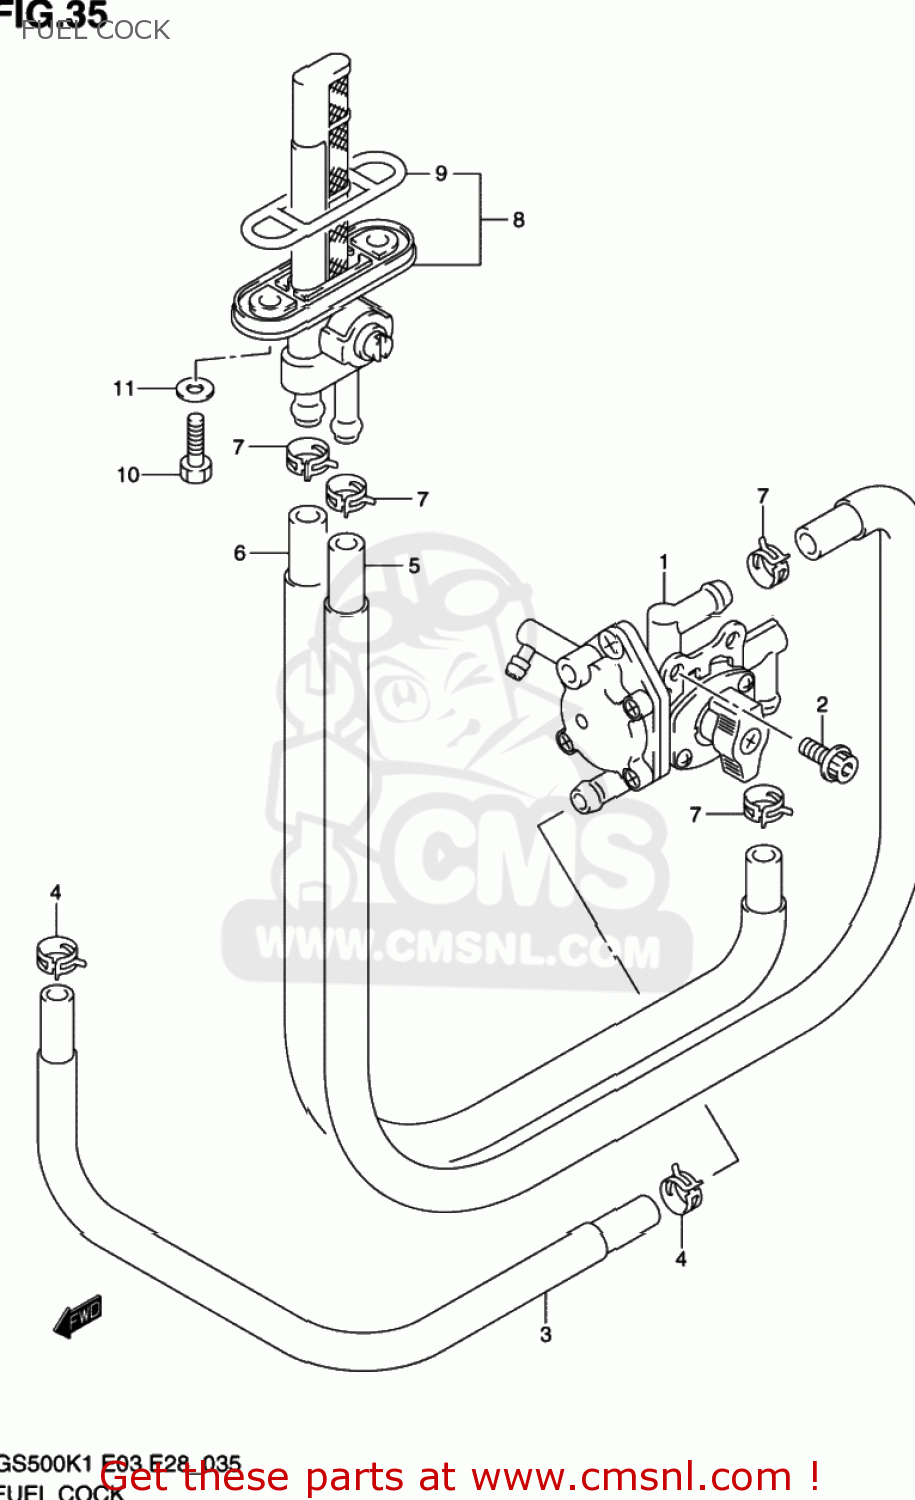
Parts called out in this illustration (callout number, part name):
1	COCK ASSY,FUEL NO.1
2	BOLT
3	HOSE,FUEL
4	CLIP
5	HOSE,FUEL ON
6	HOSE,FUEL RESERVE
7	CLIP
8	COCK ASSY,FUEL NO.1
9	O RING,FUEL COCK
10	BOLT(6X20)
11	GASKET(6.4X11.5X0.8) (NAS)
